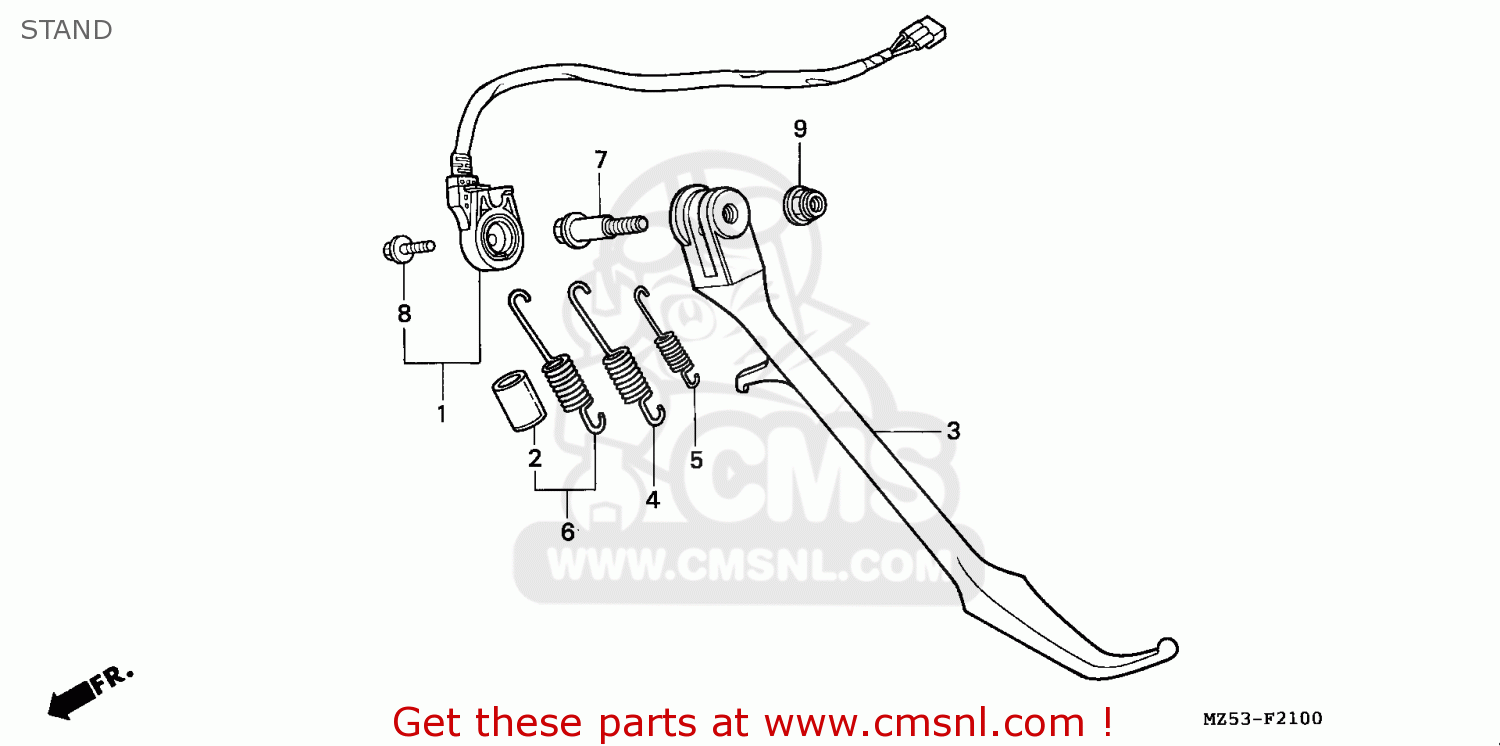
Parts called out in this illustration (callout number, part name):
1	SET,SIDE STAND SW
3	BAR,SIDE STAND
4	SPRING,SIDE STAND
7	BOLT,SIDE STAND P
8	BOLT,SPECIAL 6X16
9	NUT,SIDE STAND
